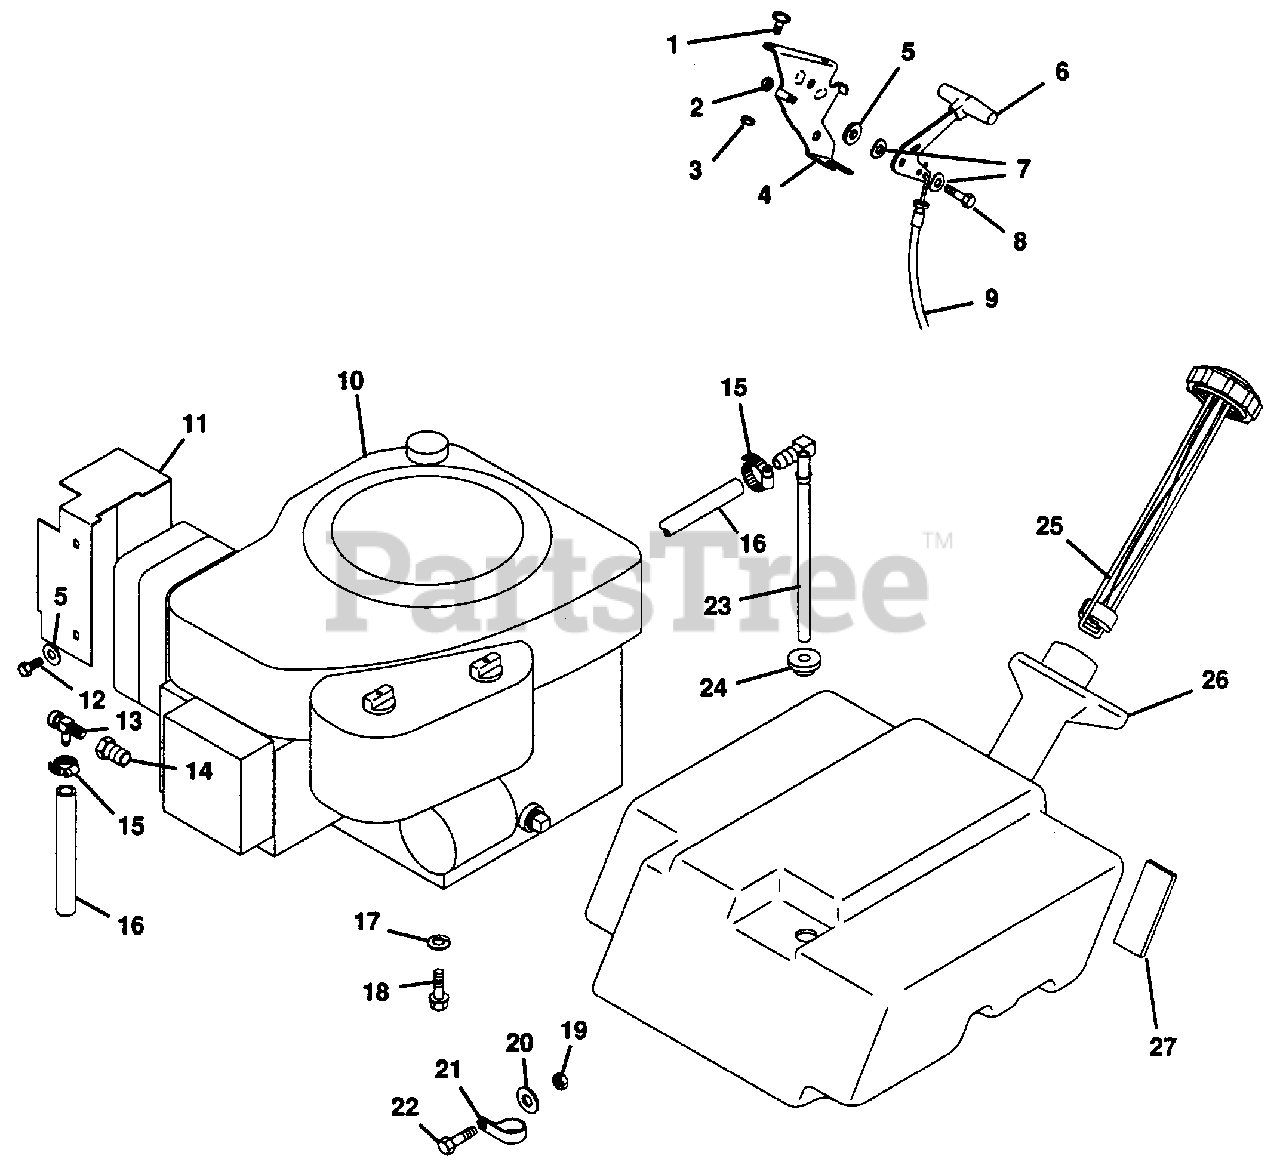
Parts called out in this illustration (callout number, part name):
1	Screw, Mach. 10-24 x .625 PHD
2	Nut, Lock 1/4-28
3	Nut, Lock 10-24
4	Bracket, Mounting L.H.
5	Washer, Flat .281 x .625 x .065
6	Assembly, Knob and Lever
7	Washer, Spring
8	Bolt, Hex 1/4-28 x .625
9	Assembly, Conduit
10	Engine, 12.5 HP B & S
10	Engine, 14 HP B & S
11	Shield, Heat
12	Bolt, M6 x 12 Plated
13	Cock, Oil Drain
14	Adapter, Oil Drain
15	Clamp, Hose
16	Line, Fuel .5 OD x .25 ID
17	Washer, Lock 5/16 Reg.
18	Screw, Taptite 3/8-16 x 1.25
19	Nut, Lock 5/16-18
20	Washer, Flat .313 x .875 x .065
21	Clamp, Steel .625
22	Bolt, Hex 5/16-18 x 1.00
23	Fitting, Tank
24	Bush., .563 x 1.06 x .688
25	Fuel Gage and Cap
26	Tank, Fuel
27	Pad, Gas Tank
